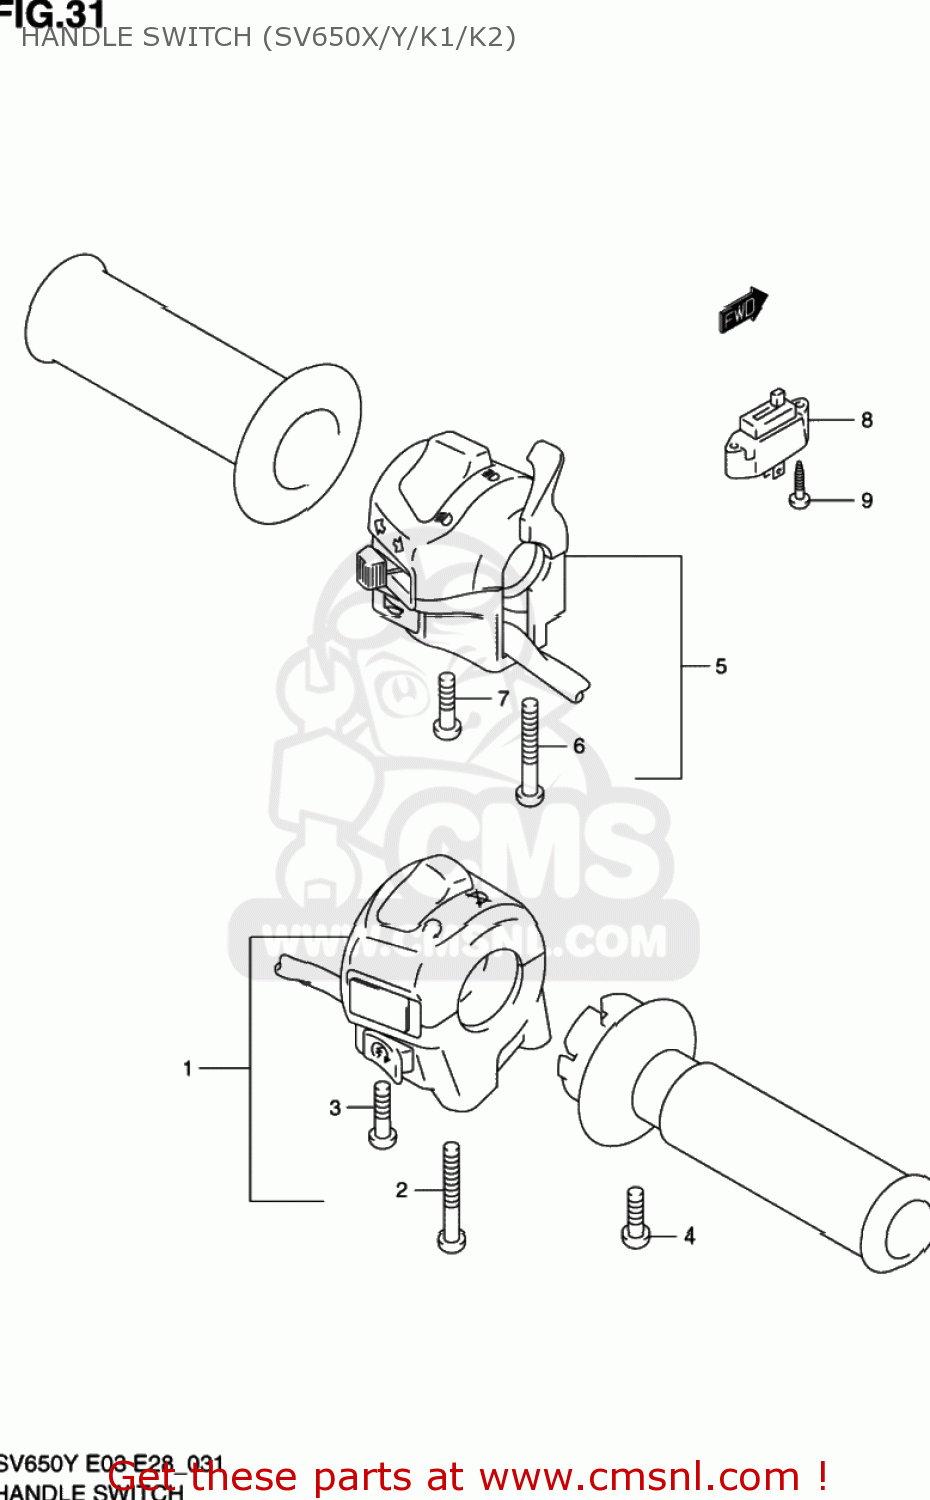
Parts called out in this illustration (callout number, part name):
1	SWITCH ASSY,HANDLE,R
2	SCREW
3	SCREW
4	SCREW
5	SWITCH ASSY,HANDLE,L
6	SCREW, 5X45
7	SCREW(5X25)
8	SWITCH ASSY,CLUTCH
9	SCREW
